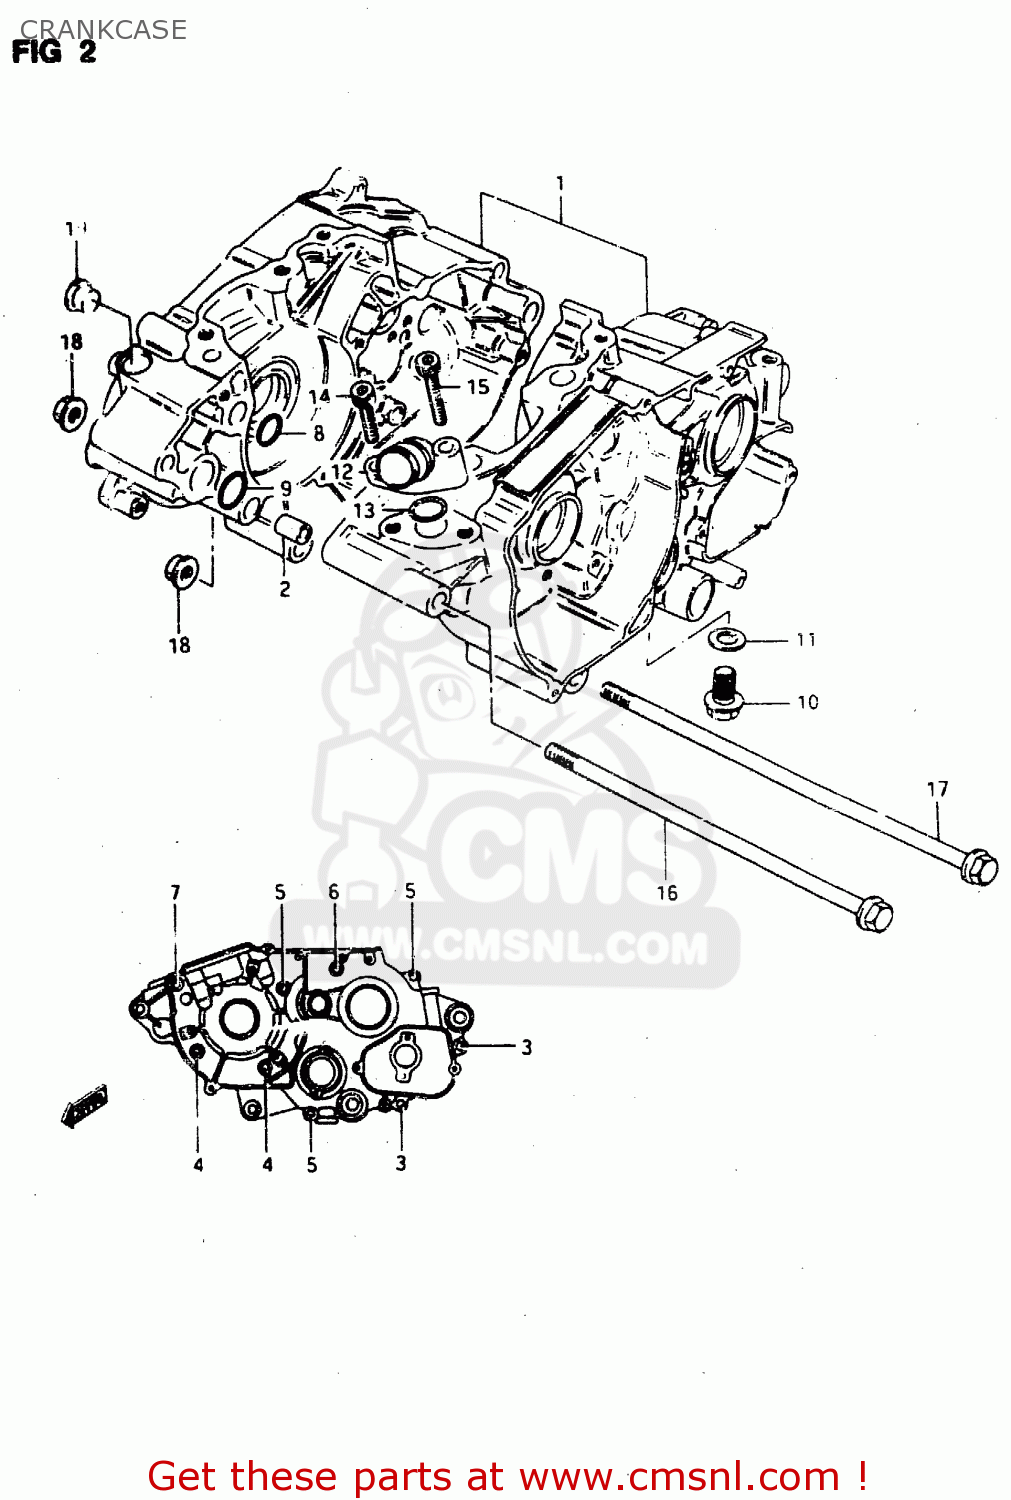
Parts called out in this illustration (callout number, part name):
1	CRANKCASE SET
2	PIN
3	SCREW 6X30
4	SCREW
5	SCREW
6	SCREW
7	SCREW
8	O-RING (D:2.4 ID:12.3)
9	O RING(D:2.4,ID:15.8)
10	BOLT
11	GASKET(10X14X3.6) (NAS)
12	CONNECTOR,WATER INLET
13	O RING(D:2.4,ID:15.8)
14	BOLT,CRKCASE,R
15	BOLT
16	BOLT (8X120)
17	BOLT (8X140)
18	NUT
19	PLUG(OD:22)
